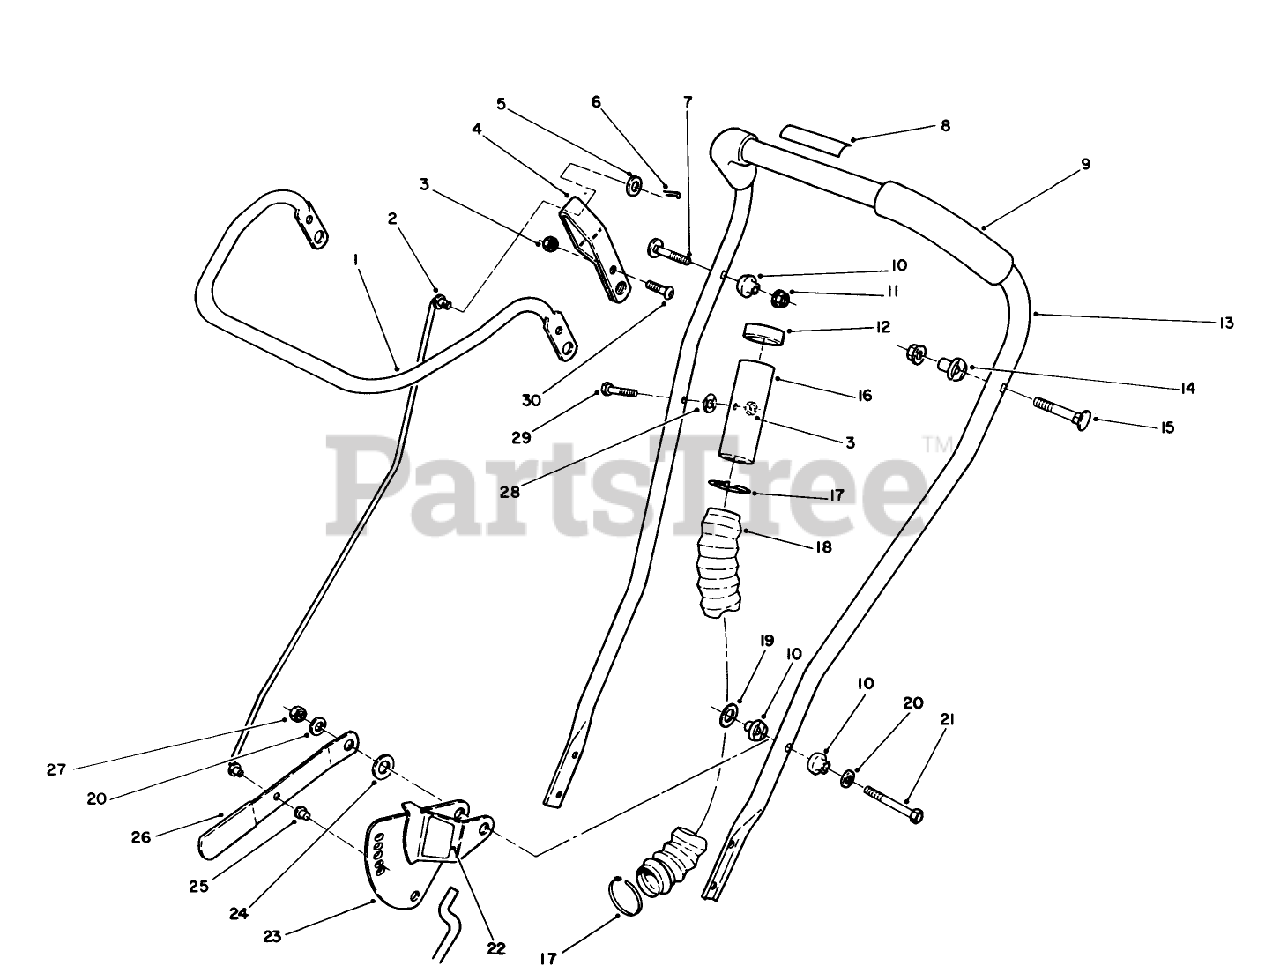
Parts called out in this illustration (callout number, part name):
2	UPPER CONTROL ROD *
3	NUT-LOCK, NI
5	WASHER-FLAT
6	PIN-COTTER
7	SCREW-HANDLE
11	NUT-LOCK, NI
12	BLACK CAPLUG
13	UPPER HANDLE *
14	SPACER-SUPPORT
17	TIE-CABLE
20	WASHER-PLAIN
21	SCREW-HH
24	WASHER
25	PUSHNUT
27	NUT-LOCK, NI
28	WASHER
29	SCREW-HH
30	SCREW-HSBH
